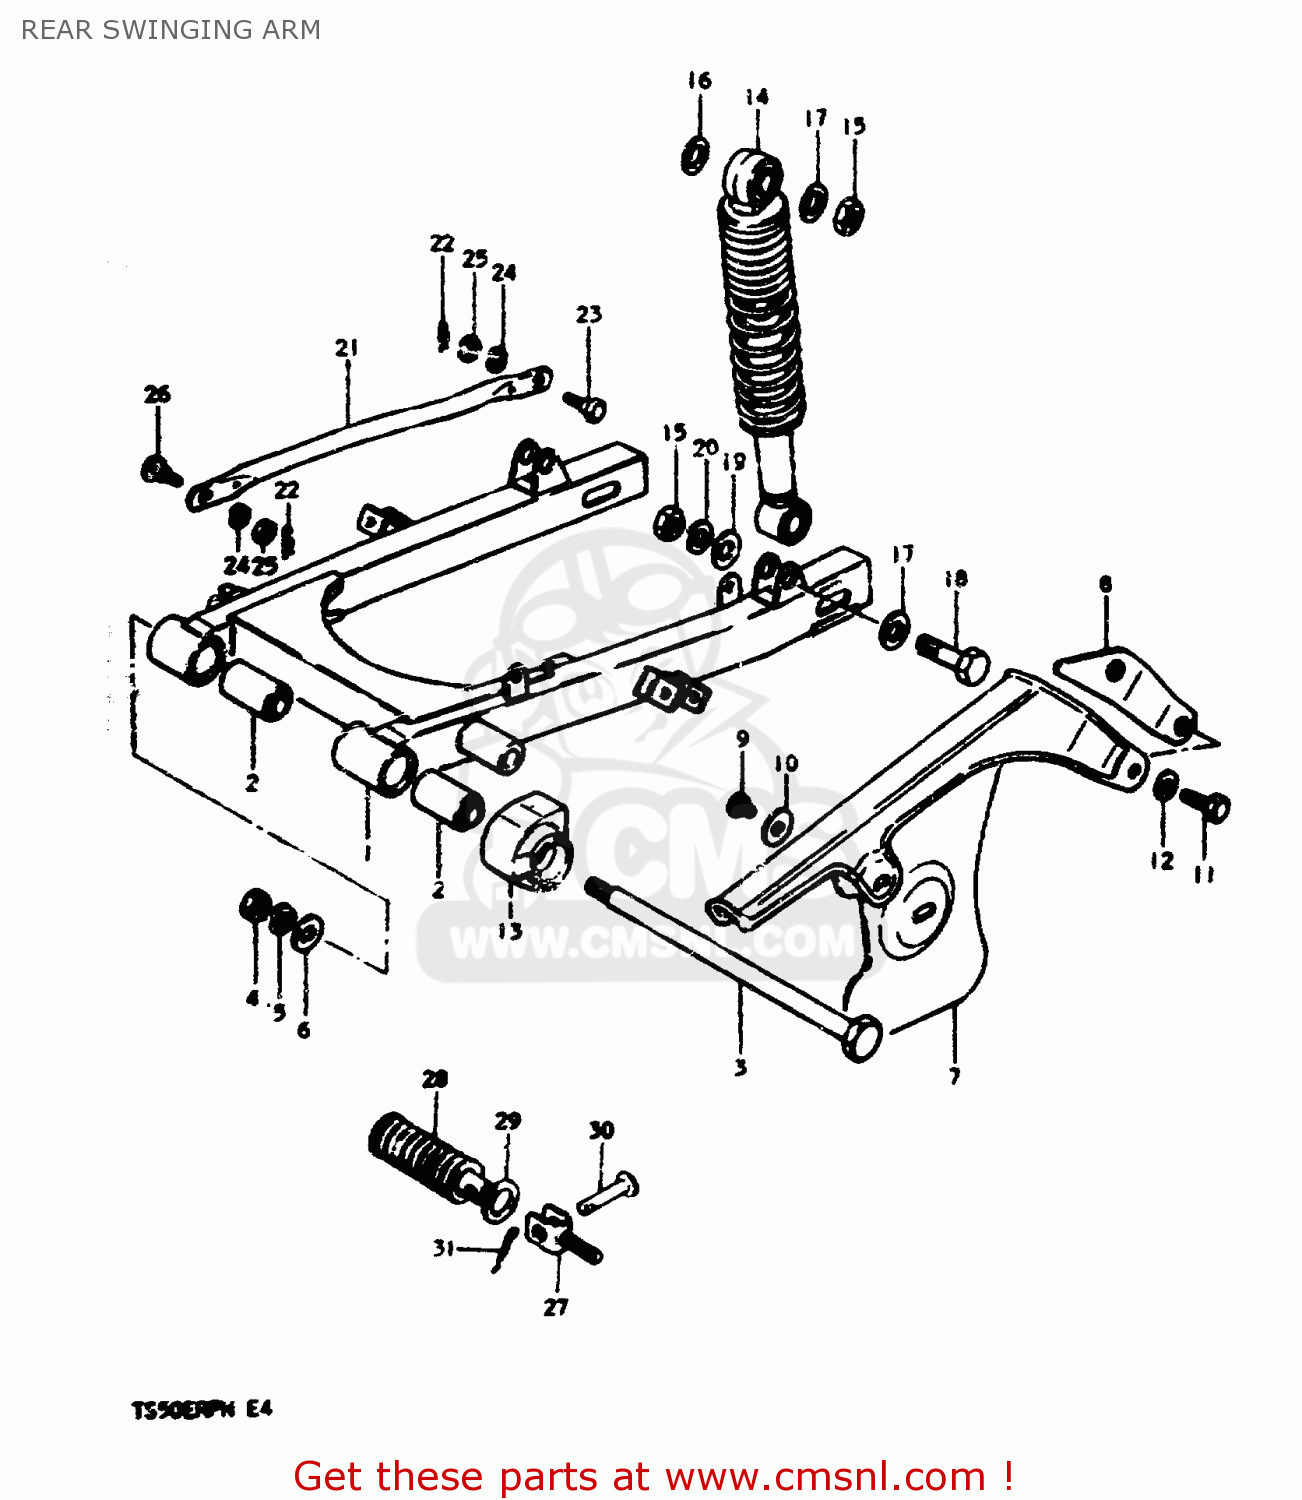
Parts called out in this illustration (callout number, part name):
1	SWINGING ARM, REAR
2	BUSH
3	SHAFT,REAR SWING ARM
4	NUT
5	LOCK WASHER
6	WASHER
7	CASE,CHAIN
8	REINFORCEMENT,CHAIN CASE
9	BOLT(6X8)
10	WASHER
11	BOLT, UPPER
12	WASHER 6MM
13	BUFFER
14	SHOCK ABSORBER, REAR
15	NUT
16	WASHER
17	WASHER
18	BOLT(10X36)
19	WASHER
20	LOCK WASHER
21	TORQUE LINK, REAR
22	CLIP
23	BOLT(8X26.5)
24	LOCK WASHER
25	NUT
26	BOLT(8X22)
27	BAR,FOOTREST RUBBER
28	RUBBER,PILLION FOOTREST
29	WASHER (19.5X32X2)
30	PIN
31	PIN 20X20
